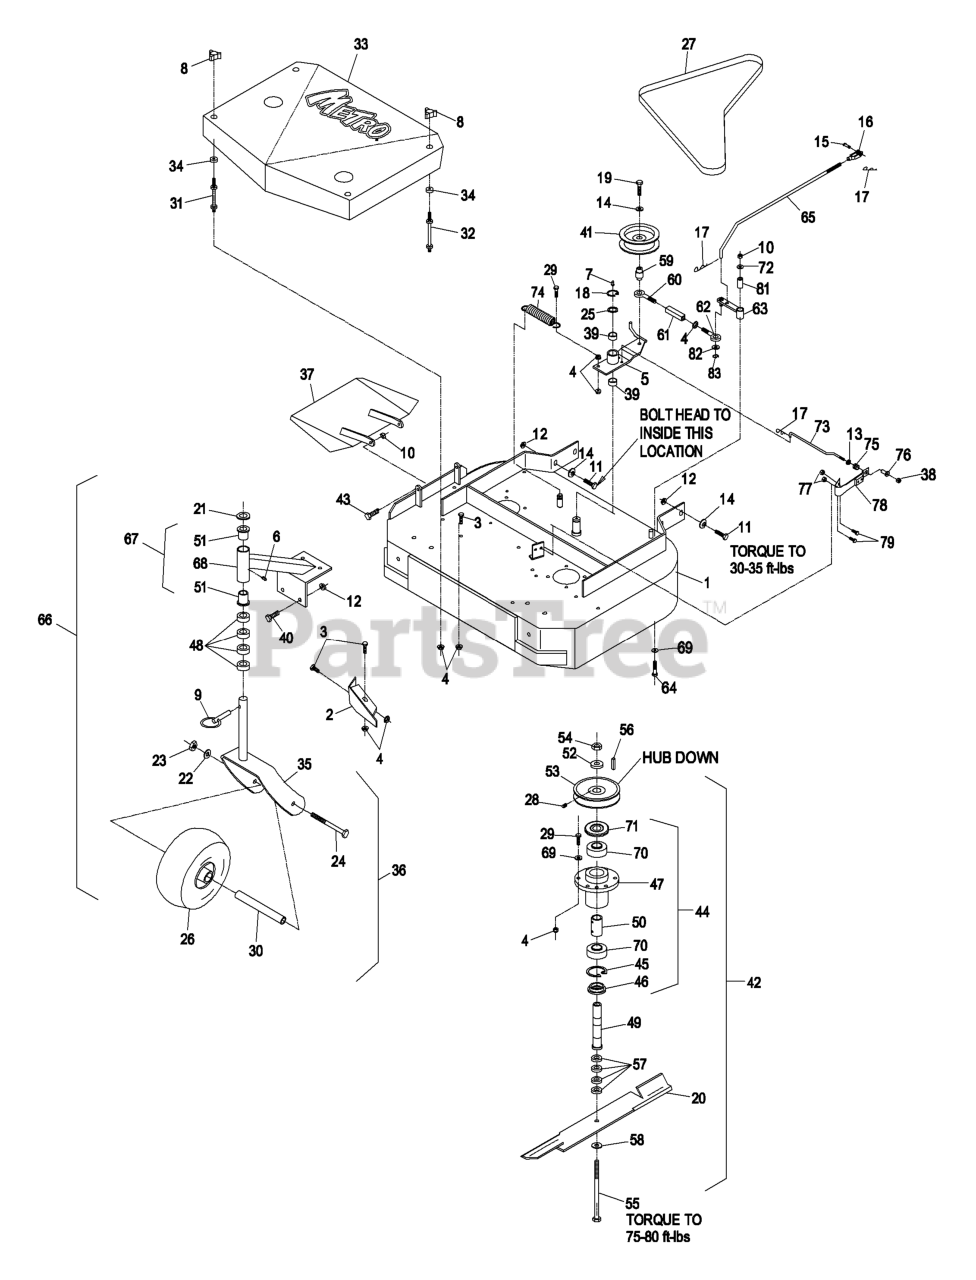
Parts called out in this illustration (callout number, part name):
1	ASM,DECK 36 RIGID
2	BAFFLE-DOGLEG
3	SCREW-HH
6	FITTING-GREASE
7	FITTING-GREASE
8	KNOB-3 PRONG
10	NUT-LOCK, NI
11	SCREW-HH
12	NUT-HHF, WHIZ
13	RING-PUSH ON
14	WASHER-BELLEVILLE
15	PIN-CLEVIS
16	YOKE-ADJUSTABLE
17	PIN-COTTER
18	RING-RETAINING, EXT
19	SCREW-HH
21	WASHER-FLAT
22	WASHER-LOCK
23	NUT-HH
24	SCREW-HH
25	WASHER-SPINDLE
27	BELT,BLADE METRO 36
28	SCREW-SET
29	SCREW-HH
30	SPACER FRONT CASTER
31	STUD-SHIELD, BELT (SHORT)
32	STUD-SHIELD, BELT (LONG)
36	ASM,CASTER/WHEEL
37	WLD,CHUTE 36 RIGID
38	NUT-LOCK, NI
39	SLEEVE-BEARING
40	SCREW-HH
43	SCREW-HH
45	RING-SNAP
46	SPACER-GUARD, BOTTOM
48	SPACER-CASTER
49	TUBE-SPINDLE, SHORT
50	SPACER-BEARING
51	BEARING-FLANGED
52	WASHER-RETAINER, SHEAVE
53	SHEAVE
54	NUT-HEX
55	SCREW-CAP, HH
58	WASHER-SPRING
59	BUSHING-ENGAGEMENT
60	EYEBOLT-THREAD, LH
61	BODY-TURNBUCKLE
62	EYEBOLT-THREAD, RH
63	ARM-ASSIST, 32/36
64	SCREW-HH
65	ARM-ASSIST, LINKAGE
66	ASM,CASTER/MOUNT
67	SUPPORT ASM
69	WASHER-SPRING
70	BEARING-JACKSHAFT
71	GUARD-BEARING, TOP
72	WASHER-FLAT
73	ROD-BRAKE
74	SPRING-EXTENSION
75	SPRING-COMPRESSION
76	SPACER-FLANGED
77	NUT-LOCK, NI
78	PAD AND SPRING ASM
79	SCREW-HH
81	TUBE-PIVOT
82	WASHER-PLAIN
83	RING-RETAINING, EXT
84	KIT, SP CASTER WHEEL REPL
